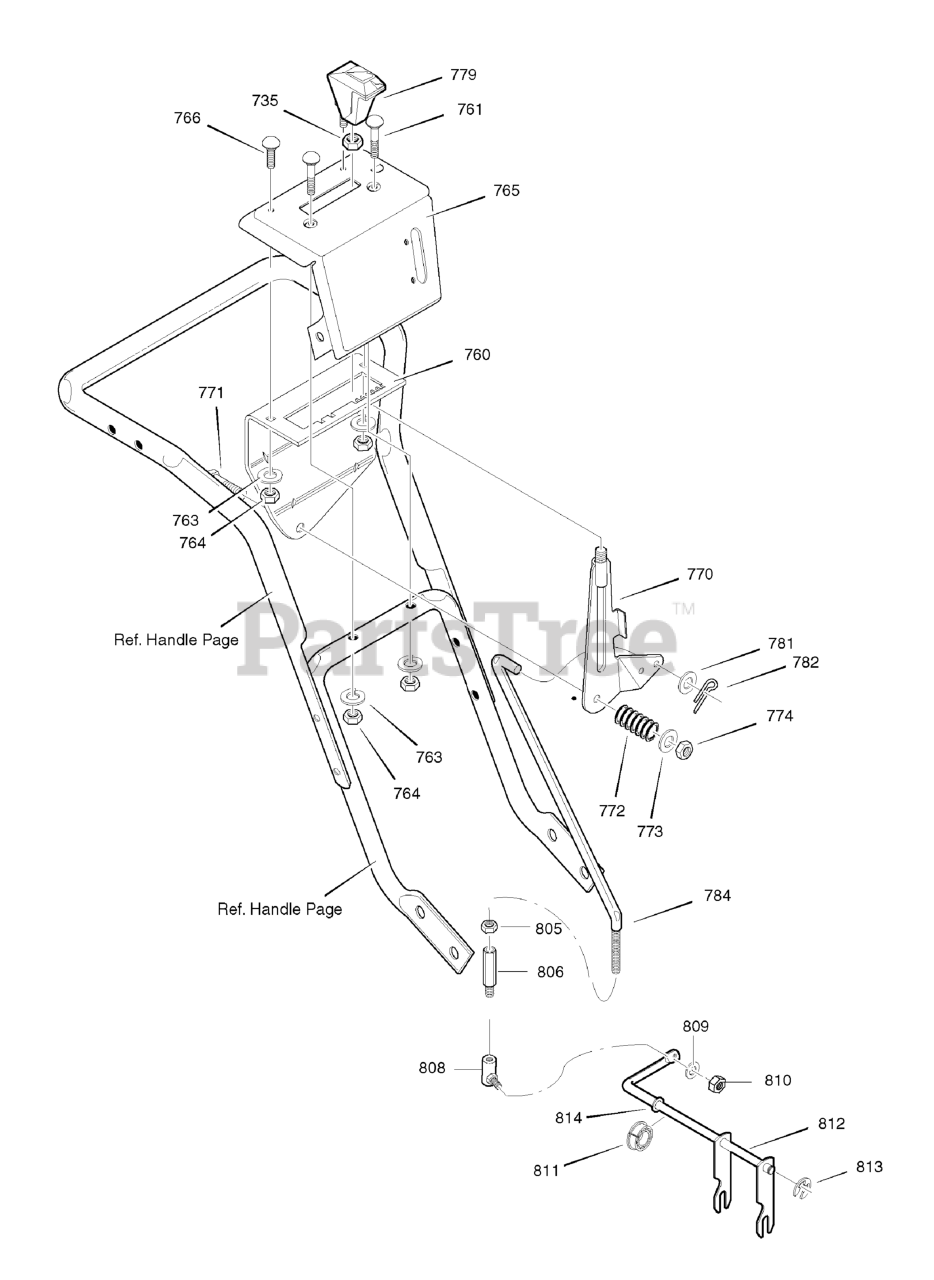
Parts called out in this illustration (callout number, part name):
735	NUT, 3/8-16 HEXJAM
760	BRACKET, SHIFT CONTROL
761	CARRIAGE BOLT, 1/4-20 X 2.00
763	WASHER, SPLIT
764	NUT, 1/4-20 HEX
765	CONTROL PANEL
766	CARRIAGE BOLT, 1/4-20 X .63
770	SHIFT LEVER ASSEMBLY
771	SCREW, 5/16-18 X 1.75
773	FLATWASHER
774	NUT, 5/16-18 NYLON HEX
781	WASHER, FLAT .349 X .69 X .066
782	PIN, COTTER
784	ROD, SPEED CONTROL
805	NUT, 5/16-24
806	ADAPTER, SPEED ROD -YZ
808	BALLJOINT, STEEL -YZ
809	WASHER
810	NUT, 5/16-24
811	FLANGED BEARING
812	ROD ASSEMBLY, YOKE PANEL
813	RING, RETAINER
